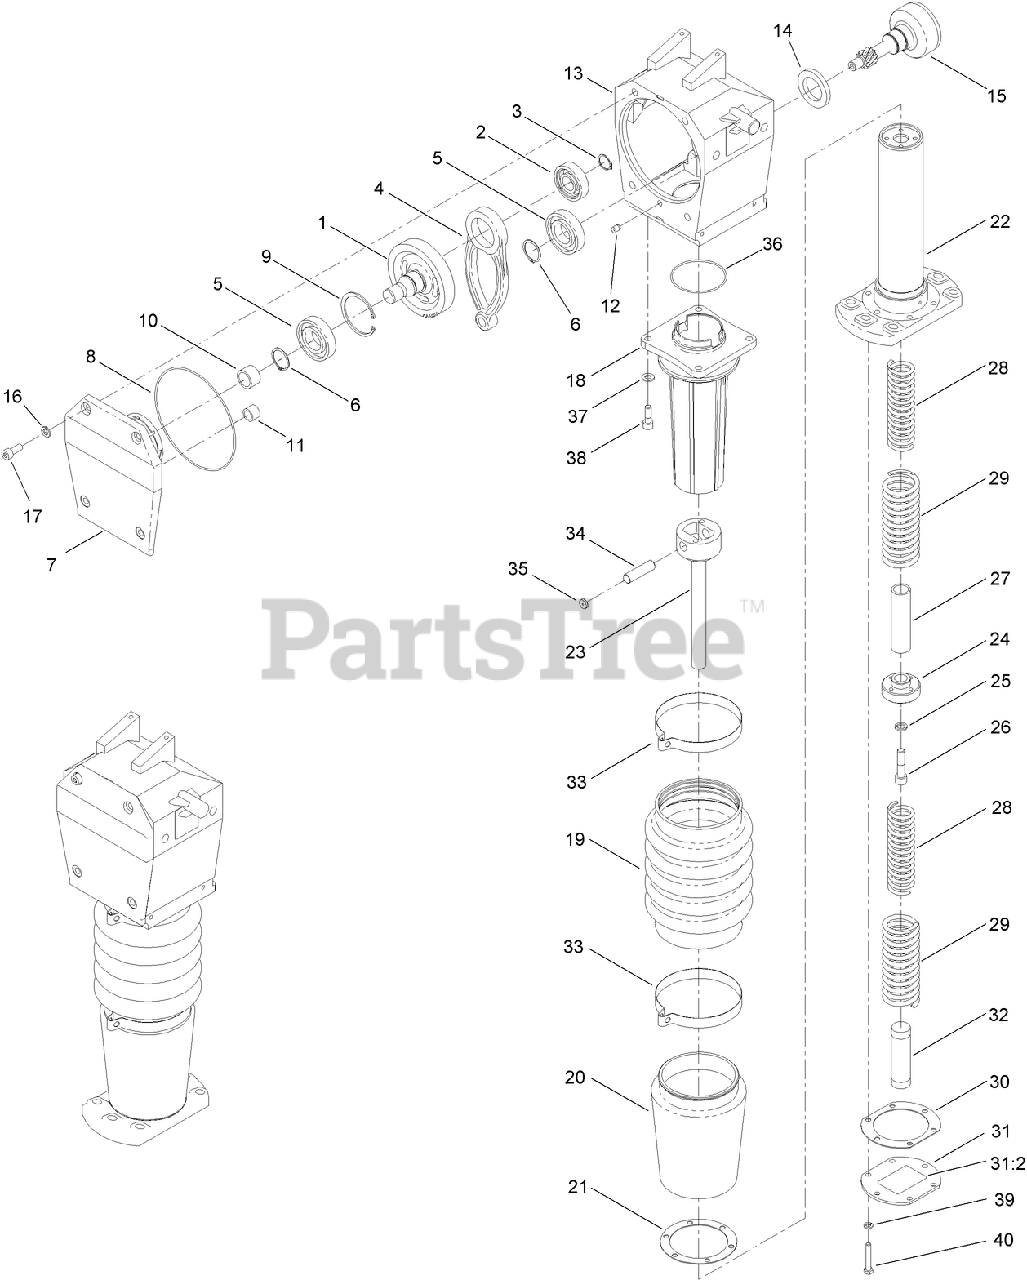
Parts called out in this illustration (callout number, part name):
1	GEAR-HELICAL
2	BEARING-BALL
3	RING-EXTERNAL
4	ROD-CONNECTING
5	BEARING-BALL
6	RING-SNAP, EXTERNAL
7	COVER-FRONT
8	O-RING
9	RING-INTERNAL
10	BEARING-NEEDLE
11	BEARING-NEEDLE
13	GEARCASE
14	SEAL-SHAFT
15	PINION
16	WASHER-LOCK, SPRING
17	SCREW-HSH
18	GUIDE-TUBE
19	BOOT-STOMPER
20	COVER-HOUSING, SPRING
21	GASKET-HOUSING, SPRING COVER
22	HOUSING-SPRING
23	ROD-PISTON
24	PUCK-PISTON
25	WASHER-LOCK
26	SCREW-HSH
27	SNUBBER-SPRING, UPPER
28	SPRING-COMPRESSION, INNER
29	SPRING-COMPRESSION, OUTER
30	GASKET-COVER, SPRING
31	BOTTOM SPRING COVER ASM
31:2	DECAL-WARNING, SPRING
32	SNUBBER-SPRING, LOWER
33	CLAMP-BOOT, STOMPER
35	BUTTON-PIN, CAPTIVATOR
36	O-RING
37	WASHER-FLAT
38	SCREW-HSH
39	WASHER-LOCK
40	Screw-HH
